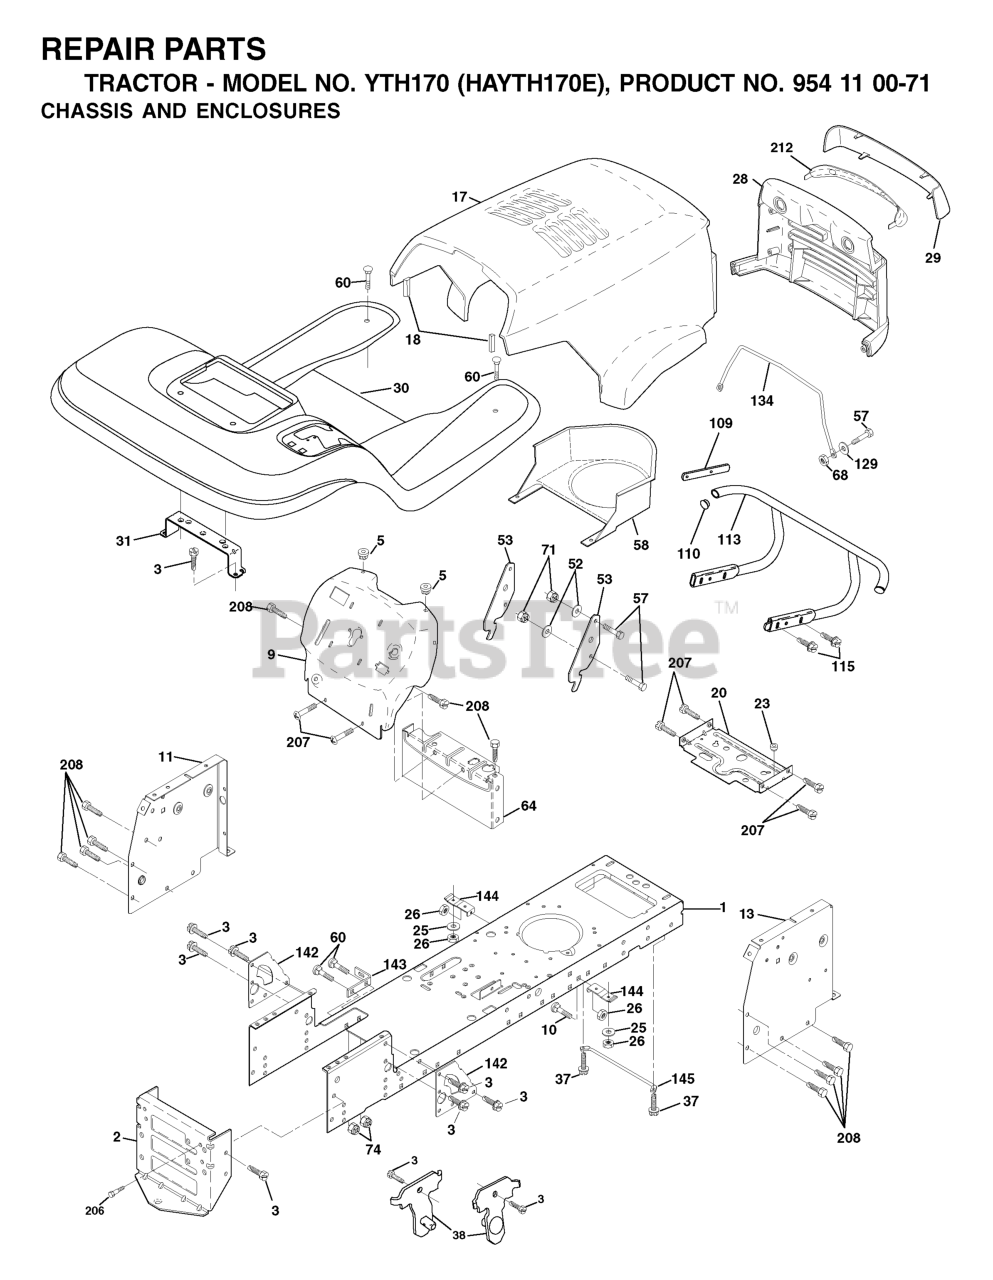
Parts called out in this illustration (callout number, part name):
2	DRAWBAR
3	SCREW 3/8-16X3/4
5	BUMPER.RUBBER.HOOD
9	DASH SLKSCR
10	BOLT D
11	PANEL DASH LH
13	PANEL ASM, DASH RH
17	HOOD
18	BUMPER HOOD T
20	PLATE MTG
23	BUSHING.SNAP.NYL.BLK.
25	WASHER
26	NUT
28	GRILL
29	LENS
30	FENDER FOOTREST
31	BRACKET.SUPPORT.FENDER
37	Screw 5/16-18 x 1/2 Hex, Self Tapping 5/16-18 x 1/2
38	BRACKET
53	BRACKET PNT PICK OFF LT/PL
57	BOLT
58	AIR DUCT P/L/LT
60	Bolt - Rd. Hd. Sq. Neckiage 3/8 16 x 3/4
64	DASH LOWER
68	NUT
71	NUT.CROWNLOCK.1/4
109	BUMPER BRACKET
110	PLUG PLASTIC
113	BUMPER ASM.
115	SCREW.3/8-16
134	ROD SUPPORT HOOD LT/PL HUS.
142	PLATE
143	BRACKET, SWAY BAR
144	BRACKET FOOTREST
145	ROD PIVOT CHASSIS/HOOD
206	SHOULDER BOLT 5/16-18TT
207	SCREW, 5/16-18 X 1/2
208	SCREW 3/8-16X1/2
212	INSERT LENS REFLECTOR
